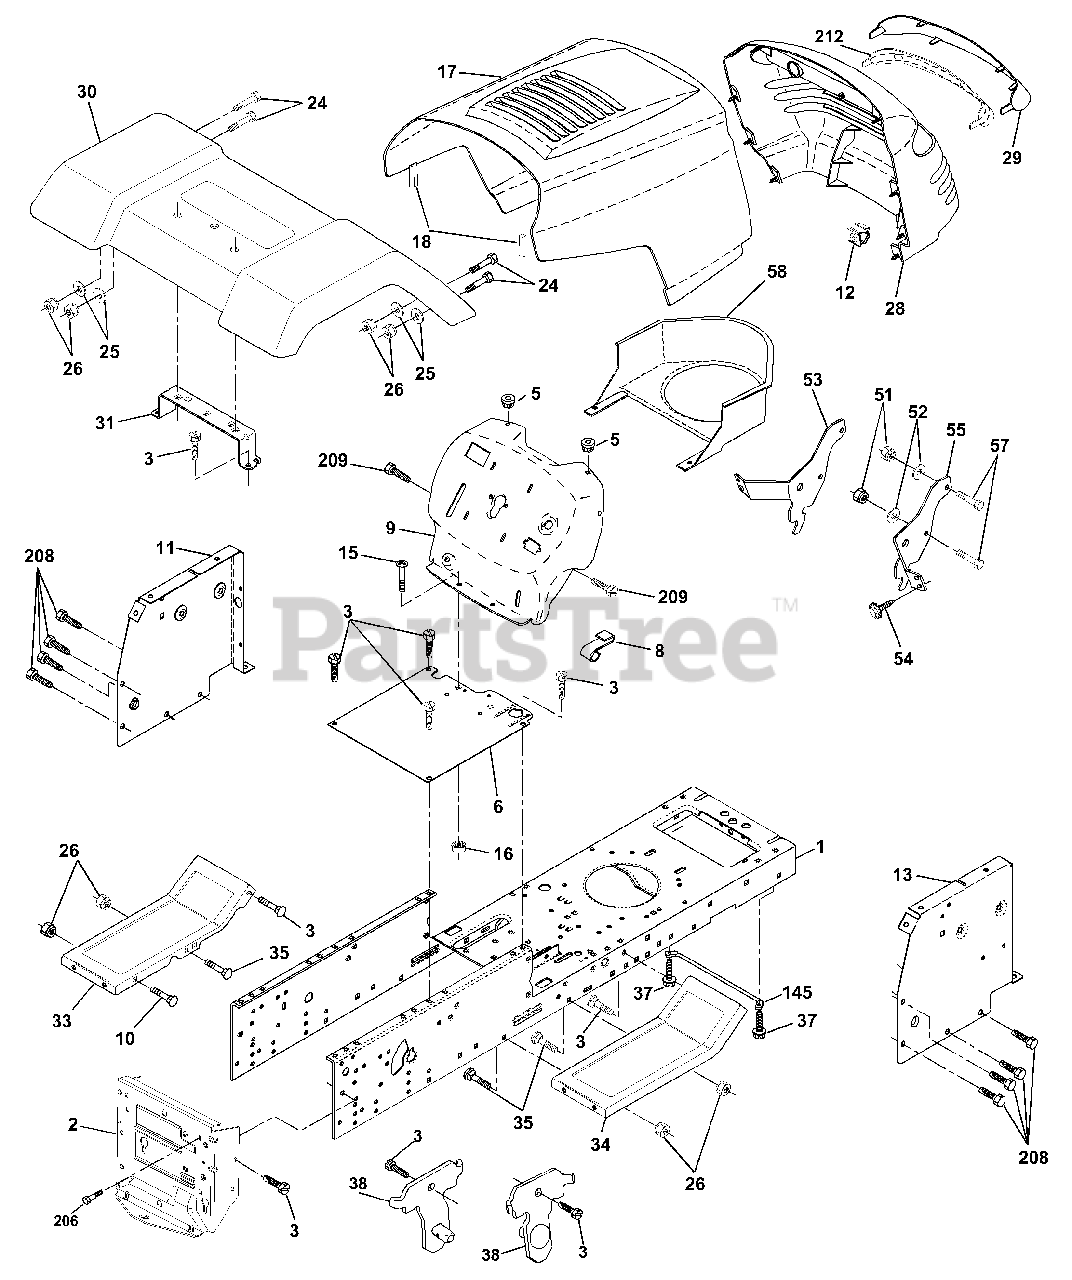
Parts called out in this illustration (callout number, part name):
2	Drawbar, Stretch
3	Screw 3/8-16 x 3/4
4	Washer 13/32 X 3/4 X 16 Ga.
5	Bumper, Hood/Dash
6	Saddle Silkscreen Flt Sdl
8	Clip Retainer Slide-On
9	Dash
10	Bolt, Carriage 3/8-16 x 1
11	Panel Dash LH
12	Clip Tinnerman Grille P.L
13	Panel Slkscr Dash RH
14	Screw Thdrol 3/8-16 x 1/2 Ty-tt
15	Screw Mach TRHD 5/16-18unc x 3/4
16	Nut Keps 5/16-18 Unc
18	Bumper Hood
24	Bolt Fin Hex 3/8-16unc X 1 Gr. 5
25	Washer 13/32 X 13/16 X 12 Ga
26	Nut Lock Hex w/Ins 3/8-16 Unc
28	Grille/Lens Asm.
29	Lens Grille Private Label
31	Bracket Fender Repl 109873x
33	Footrest Pnt LH Perf
34	Footrest Pnt RH Perf
35	Bolt Rdhd Sht Sqnk 3/8-16 X 3/4
37	Screw Thdrol 5/16-18 x 1/2 TYT
38	Bracket Asm. Pivot Mower Rear
51	Nut Lock W/Insert 1/4-20unc
52	Washer 9/32 x 7/8 x 16 Ga.
53	Bracket Grille Lh
54	Screw Hex 8-18 x 7/8
55	Bracket Grille Rh
57	Bolt Fin Hex 1/4-20 unc x .75
58	Duct Air Engine PL/LT
145	Rod Pivot Chassis/Hood
206	Bolt Shoulder 5/16-18
208	Screw Thdrol 3/8-16 x 1/2
209	Screw Hex Wsh Thdrol 3/8-16
212	Insert Lens Reflect
